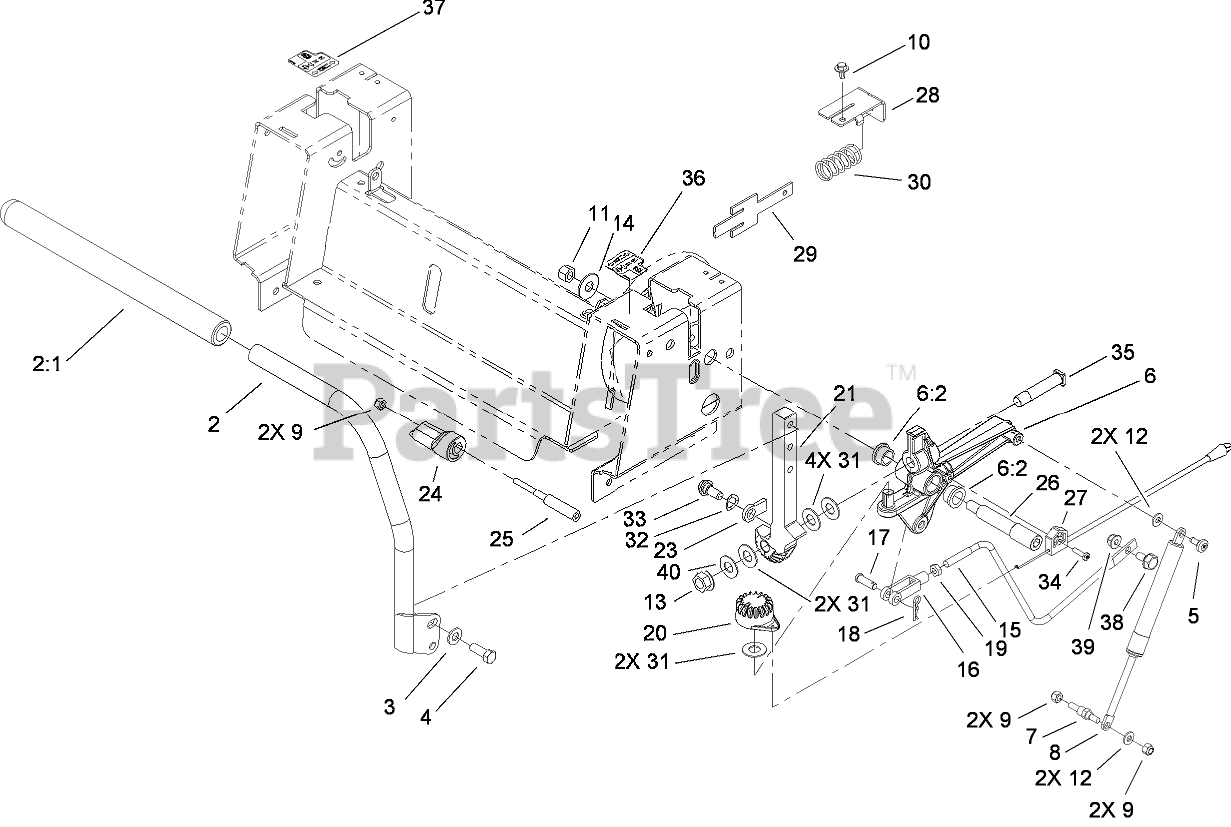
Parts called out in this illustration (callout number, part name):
2	LH HANDLE ASM
3	WASHER-FLAT
4	SCREW-HH
5	SCREW-SHOULDER
6	ACTIVATOR ARM ASM
6:2	BUSHING
7	STUD-DAMPER
8	Damper-Control, Motion
9	NUT-LOCK, NI
10	SCREW-HHFTF
11	NUT-LOCK, NI
12	WASHER-FLAT
13	NUT-HF
14	WASHER-FLAT
15	LINK-HYDRO
16	YOKE-ADJUSTABLE
17	PIN-CLEVIS
18	PIN-COTTER
19	NUT-JAM
20	GEAR-CONTROL
21	ARM-ACTUATOR, LH
23	TAB-STOP
24	ECCENTRIC
25	SCREW-ECCENTRIC
26	BOLT-SHOULDER
27	CABLE-BRAKE, PARKING
28	BRACKET-RETURN
29	PLATE-RETURN
30	SPRING-COMPRESSION
31	WASHER-PIVOT
32	WASHER-SPRING
33	BOLT-SHOULDER
34	SCREW-TORX
35	BOLT-SHOULDER
36	DECAL-CONTROL LEVER, LH
37	DECAL-CONTROL LEVER, RH
38	BOLT-SHOULDER
39	NUT-HF, NI
40	WASHER-TEFLON
